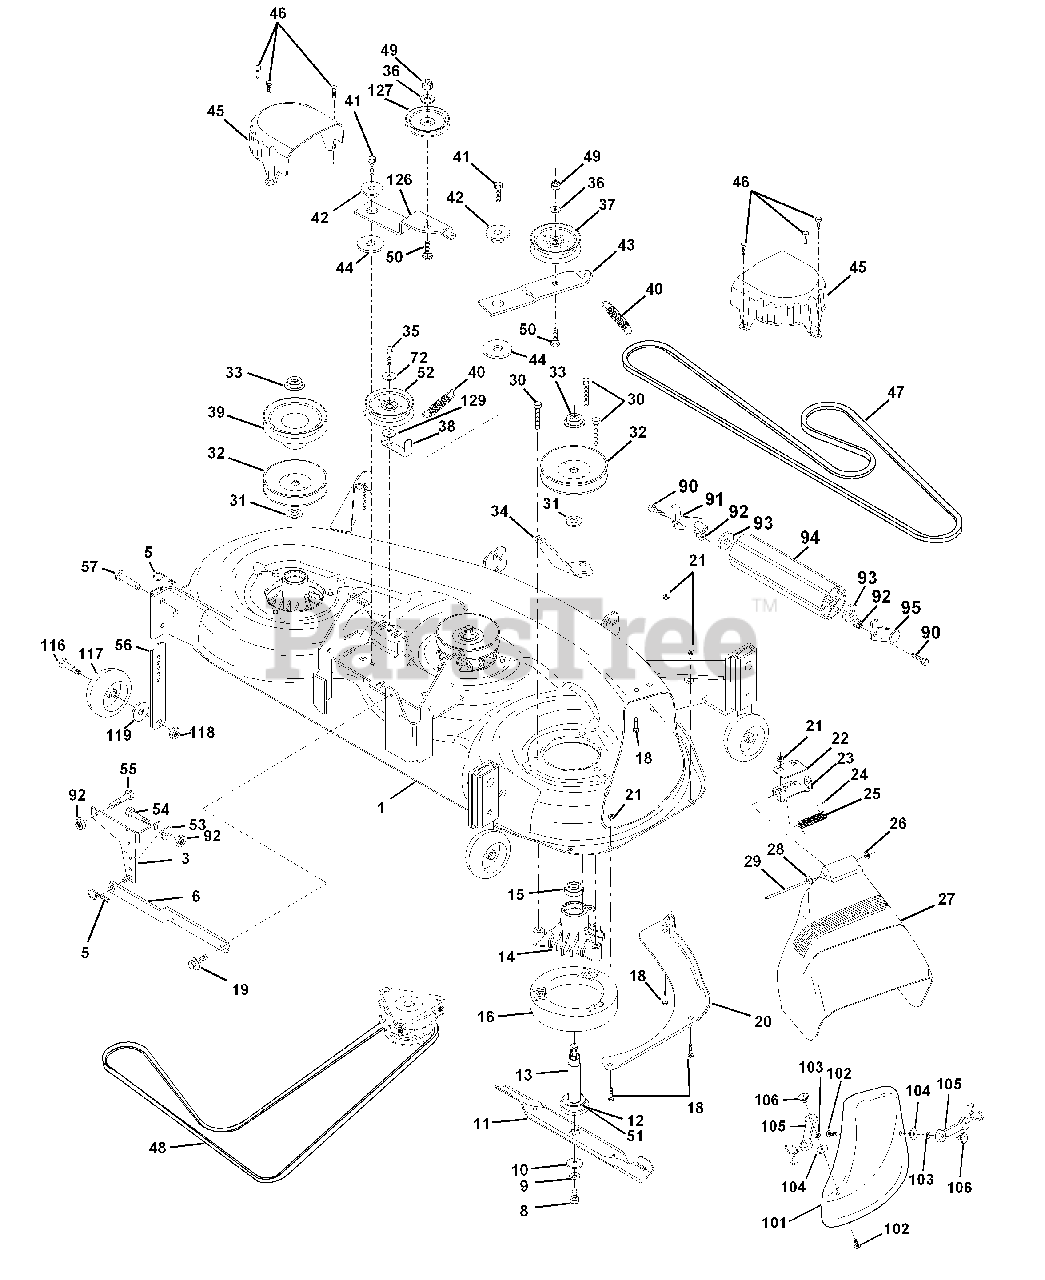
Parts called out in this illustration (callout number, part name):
1	Deck Weldment Mower HD 46 WAD
3	Bracket Asm., Sway Bar
5	Retainer Spring
6	Arm, Suspension, Rear
8	Bolt, Patched 3/8-24 x 1-1/4 Gr. 8
9	Washer, Lock Hvy., Unplated 3/8
10	Washer, Hard Blade, Mower Vented
11	Blade, 46" Mower Deck
12	Bearing, Ball, Mandrel #6204
13	Shaft Asm. w/Lower Bearing
14	Housing, Mandrel
15	Bearing, Ball, Mandrel
16	Stripper, Mower Round
18	Bolt, Carriage 5/16-18 x 5/8
19	Bolt, Hex Head, Shoulder 5/16-18
20	Baffle, Vortex Mower 46"
21	Nut, Crownlock 5/16-18 UNC
22	Stiffener, Bracket
23	Bracket, Deflector
24	Cap, Sleeve
25	Spring, Torsion, Deflector
27	Shield, Deflector Mower
28	Washer 11/32 x 5/8 x 16 Ga.
29	Rod, Hinge
30	Screw, Thdroll, Washer Head
31	Washer, Spacer Mower Vented
32	Pulley, Mandrel
33	Nut, Flg. Top Lock Cntr. 9/16
34	Anchor, Spring Deck 46"
35	Screw, Thdroll 3/8-16 x 1-3/4 Tytt
36	Washer 13/32 x 13/16 x 16 Ga.
37	Pulley, Idler, Flat
38	Keeper, Belt, Idler
39	Pulley, Idler, Driven
40	Spring, Secondary 44/46/50 Vent
41	Screw, Thdroll 3/8-16 x 1-1/4 Tytt
42	Spacer, Retainer
43	Arm, Idler Secondary
44	Washer, Hardened
45	Cover, Mandrel Deck
46	Screw, Thdroll. 1/4-20 x 5/8
47	V-Belt, Mower, Secondary
48	V-Belt, Mower, Primary
49	Nut, Crownlock 3/8-16 UNC
50	Bolt, Carriage 3/8-16 x 1-1/2 Gr. 5
51	Washer, Felt
52	Pulley Idler Flat 46 Pri. Drive
53	Washer 13/32 x 13/16 x 12 Ga.
54	Bolt Fin Hex 3/8-16unc x 1 Gr. 5
55	Bolt Rdhd Sqnk 3/8-16unc x 1
56	Bar Pnt Adjusting Wheel Gauge
57	Pin Head Rivet
72	Washer 13/32 x 1 x 16 Ga.
90	Bolt, Fin, Hex 3/8-16 UNC x 1
91	Bracket, Asm Noseroller, LH
92	Nut, Lock, Hex w/Ins 3/8-16UNC
93	Washer 17/32 x 7/8 x 16 Ga.
94	Roller, Nose 38 & 42
95	Bracket, asm Noseroller RH
101	Cover, Mulching
102	Screw
103	Washer, Lock #10
105	Latch Asm. Bagger
106	Nut, Weld
116	Bolt, Shoulder
117	Gauge Wheel
118	Nut, Centerlock 3/8-16 UNC
119	Washer 3/8 x 7/8 x 14 Ga.
126	Arm, Idler, Primary Deck 46"
127	Pulley, Idler, V-Groove Dim. 4.25
127	Mandrel Assembly
127	Mower Serv 46"
